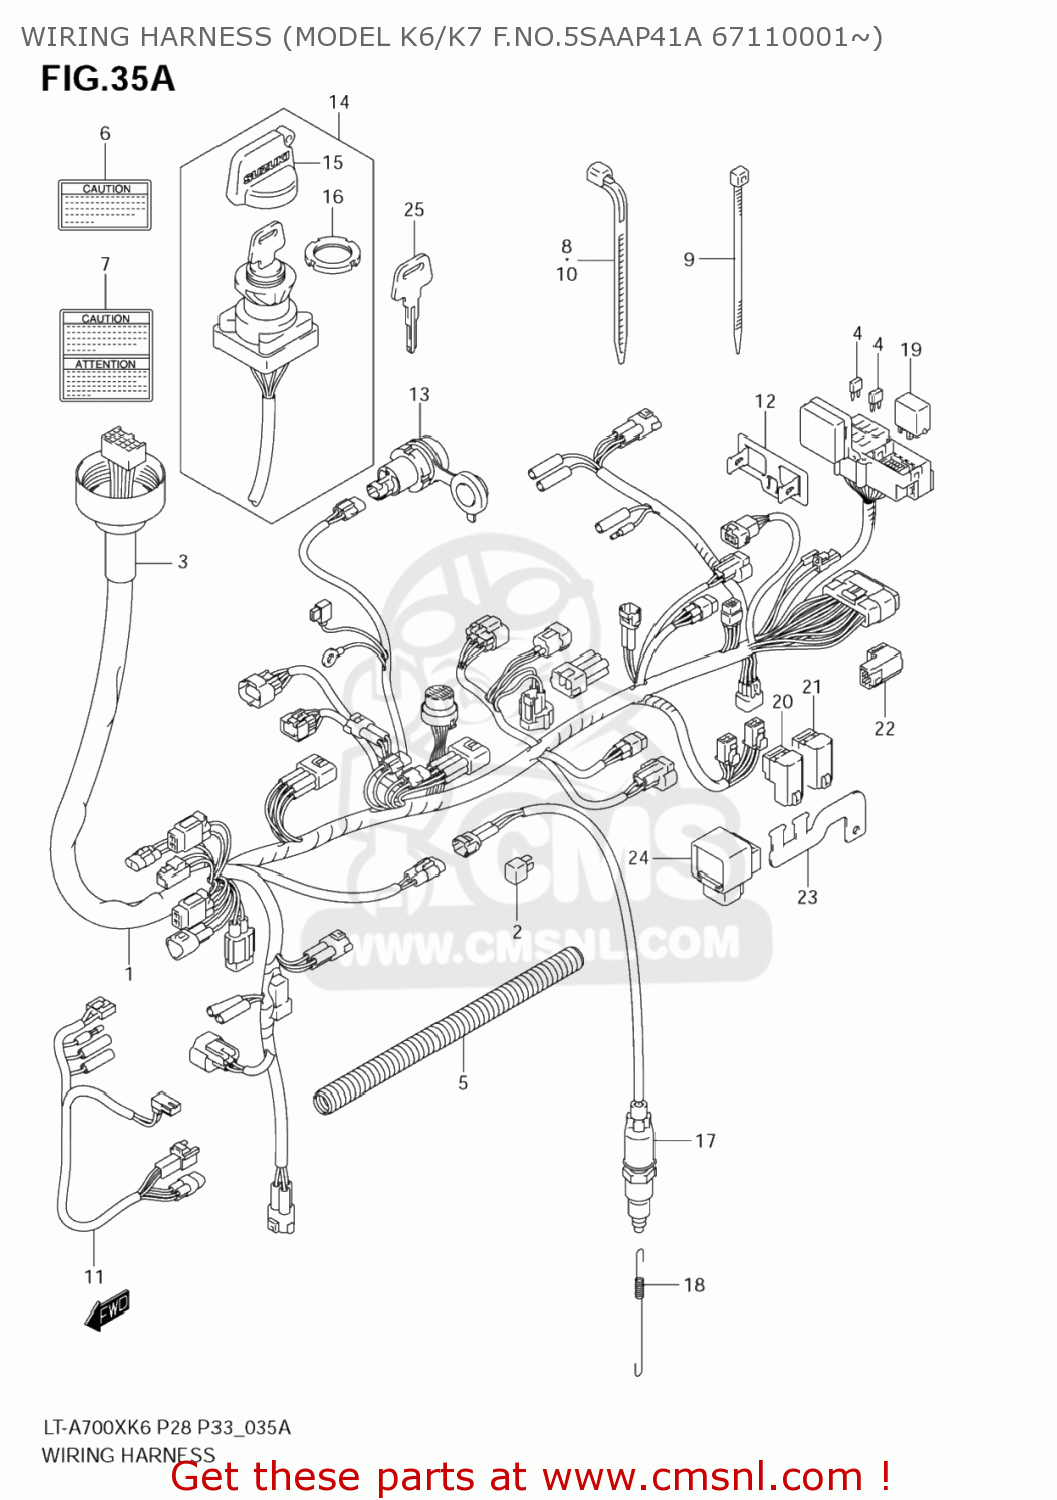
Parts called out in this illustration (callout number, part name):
1	HARNESS,WIRING
2	RECTIFIER ASSY
3	COVER,SPEED
4	FUSE(10A)
5	GUIDE,WIRING HARNESS
6	LABEL,CAUTION MAX AMP
7	LABEL,CAUTION MAX AMP
8	CLAMP(L:95)
9	CLAMP(L:145)
10	CLAMP(L:190)
11	WIRE,FR BRAKE SW LEAD
12	BRACKET,FUSE BOX
13	TERMINAL,POWER SOURCE
14	SWITCH ASSY,IGNITION
15	MASCOT,KEY
16	NUT,IGNITION SWITCH
17	SWITCH ASSY,STOP LAMP
18	SPRING
19	RELAY,NEUTRAL START
20	RELAY ASSY
21	RELAY ASSY
22	RELAY ASSY,FUEL PUMP
23	BRACKET,RELAY
24	RELAY ASSY,DRIVE
25	KEY,BLANK(TYPE:C)
